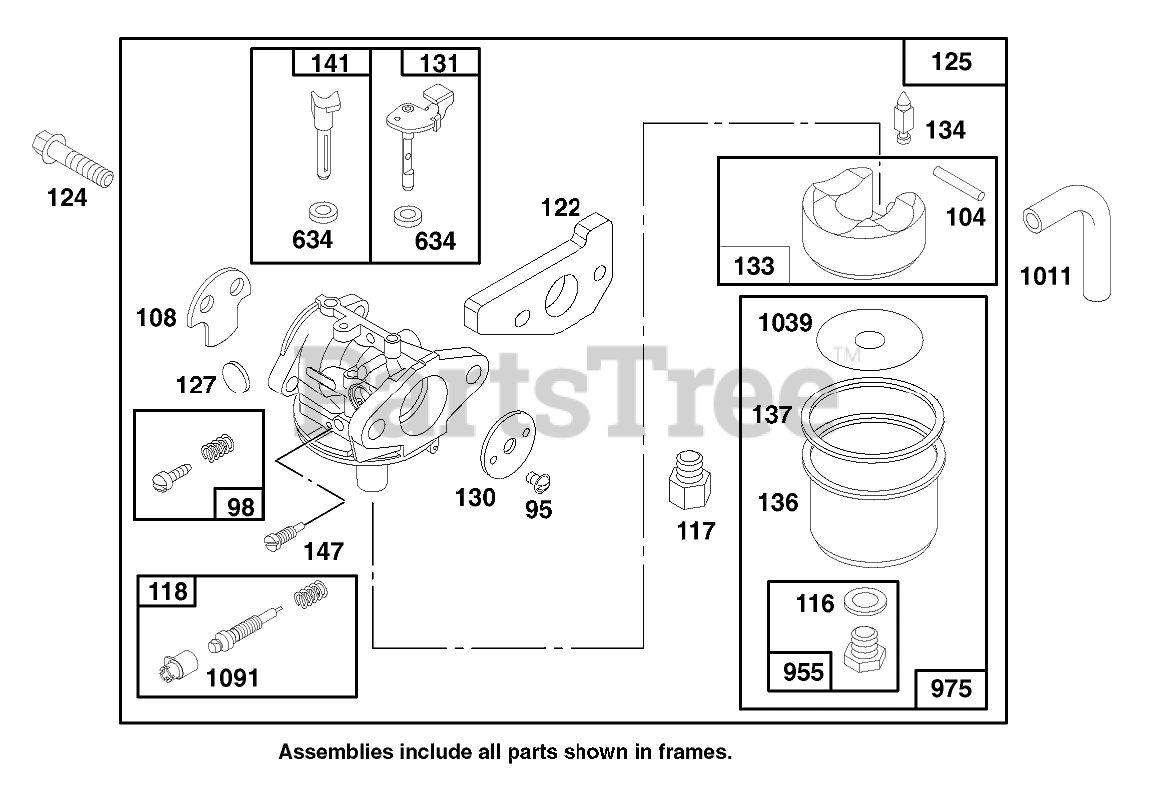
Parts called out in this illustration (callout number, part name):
1	CYLINDER ASSEMBLY
95	SCREW - ROUND HEAD
98	IDLE ADJUSTING SCREW
104	FLOAT HINGE PIN
108	VALVE - CHOKE
116	SEALING GASKET
117	Jet-Main
118	VALVE/SPRING - NEEDLE
122	ADAPTER ASSEMBLY
124	HEX HEAD SCREW
125	ASSEMBLY - CARBURETOR
127	PLUG
130	THROTTLE VALVE
131	THROTTLE SHAFT
133	FLOAT-CARBURETOR
134	Valve-Inlet (Includes Seat)
136	FLOAT BOWL
137	FLOAT BOWL GASKET
141	CHOKE SHAFT
147	JET - PILOT
188	SCREW - SEM
634	SEAL WASHER
955	HEX HEAD SCREW
975	CARBURETOR BOWL ASM
1011	VENT TUBE
1039	FLOAT LIMITER
1091	CAP - LIMITER
